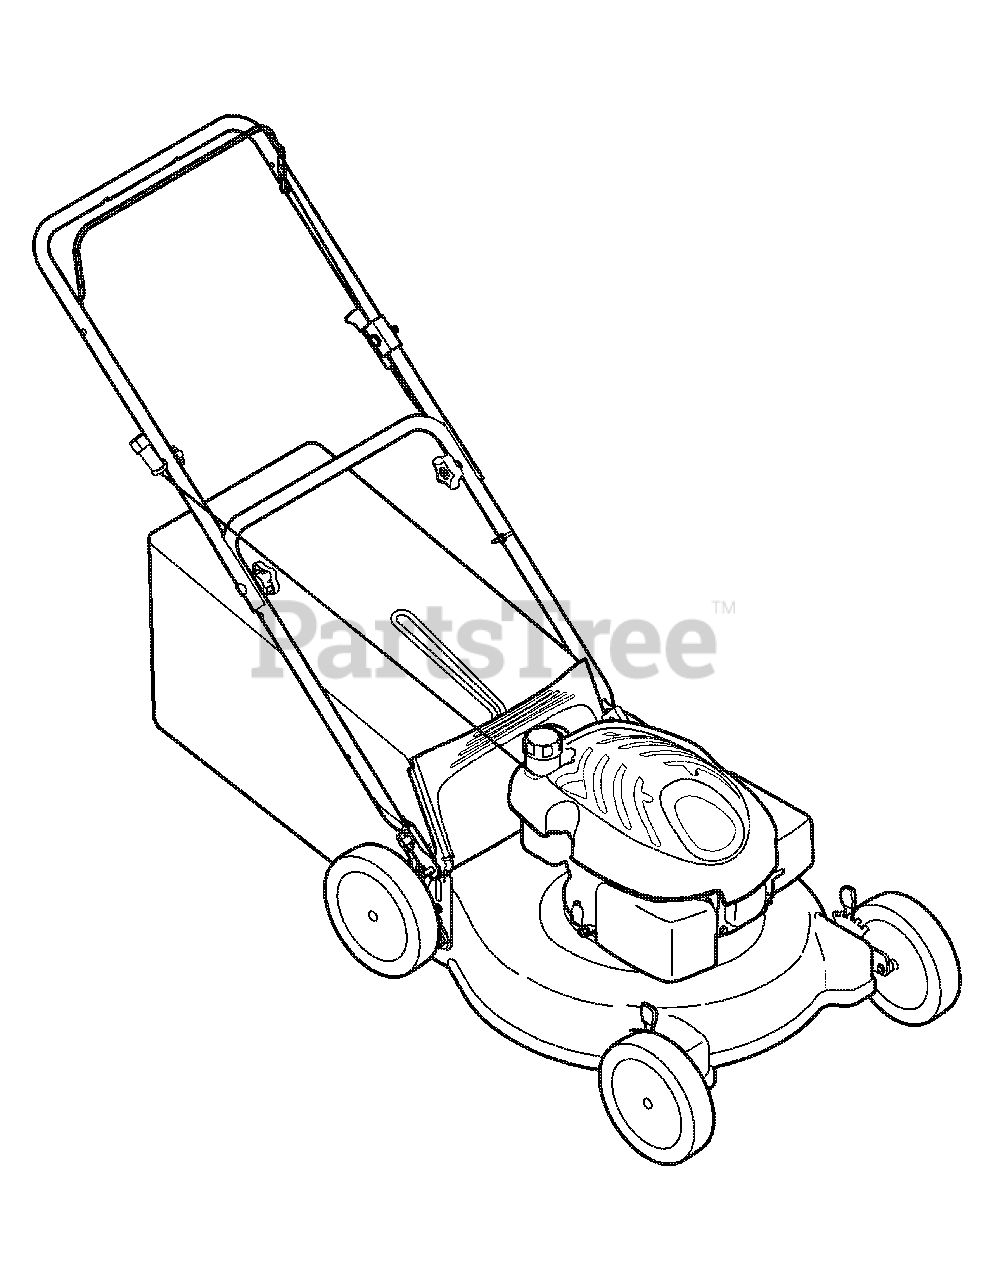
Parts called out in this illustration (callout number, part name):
NA	Pre-Filter
NA	Drive Belt
NA	Control Cable, Drive
NA	Ignition Key
